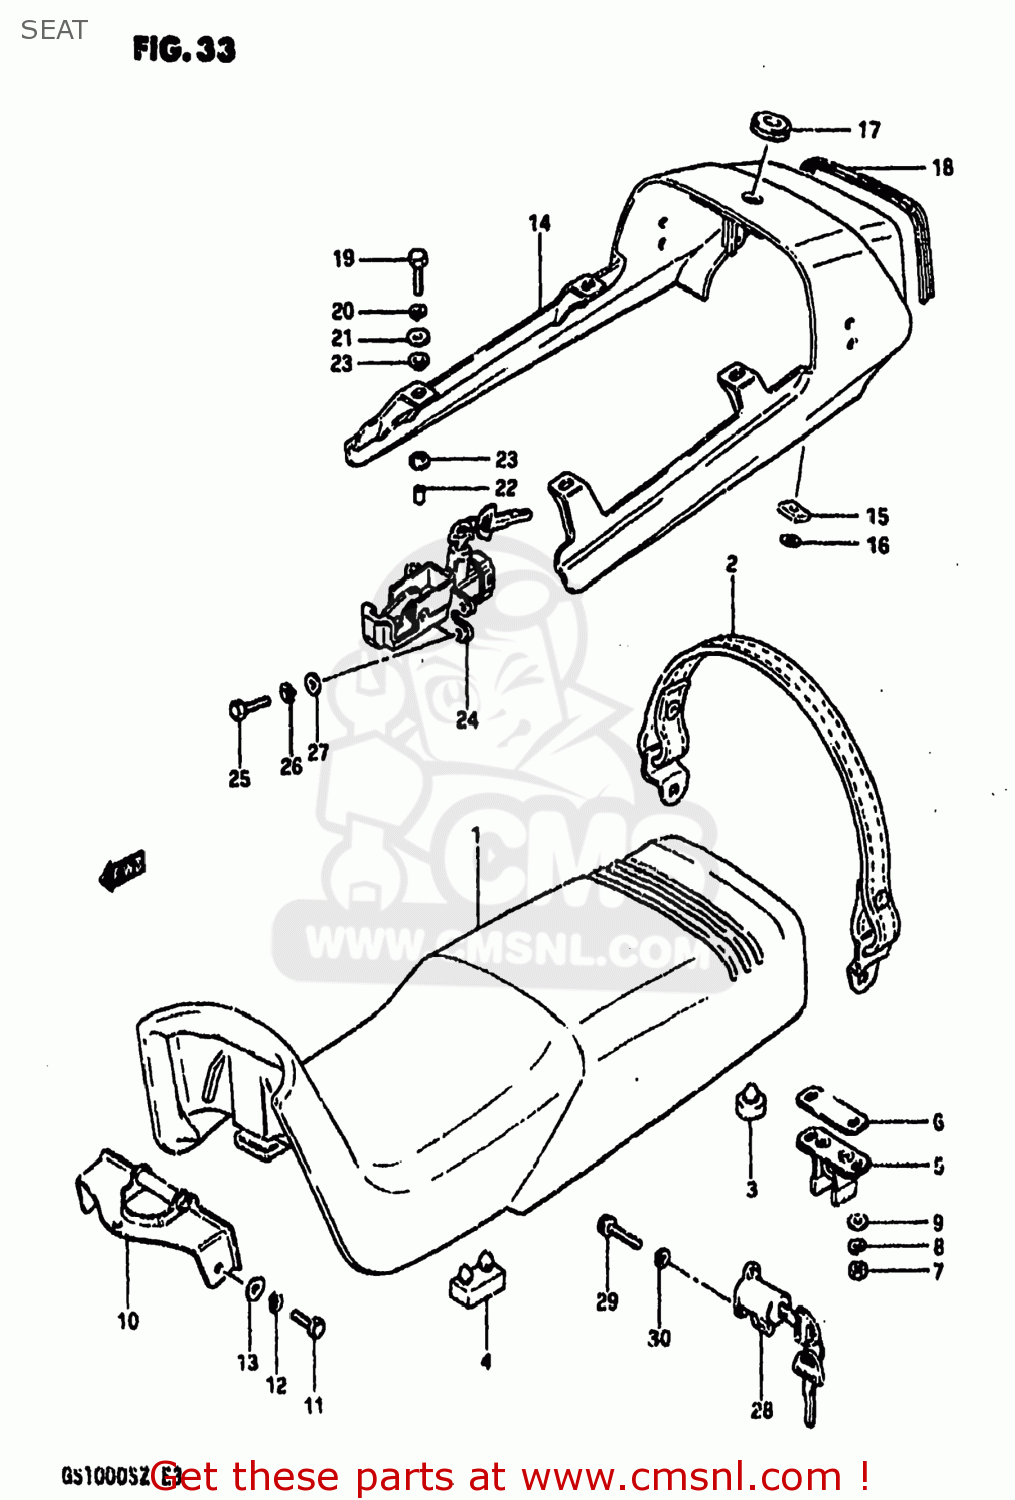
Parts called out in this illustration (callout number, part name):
1	SEAT ASSY
2	BAND,SEAT GRIP
3	CUSHION
4	CUSHION
5	STRIKER,SEAT LOCK
6	SHIM,SEAT LOCK STRIKER
7	NUT 6MM
8	LOCK WASHER
9	WASHER
10	PLATE,SEAT HOOK FR
11	BOLT
12	LOCK WASHER
13	WASHER
14	COVER ASSEMBLY,SEAT TAIL
15	CUSHION,SEAT TAIL
16	NUT
17	GROMMET,SEAT LOCK HOLE
18	MOLE,SEAT TAIL COVER
19	BOLT
20	LOCK WASHER
21	WASHER (6.5X24X1.6)
22	SPACER (7X10X12)
23	CUSHION
24	LOCK SET
25	BOLT
26	LOCK WASHER
27	WASHER
28	LOCK ASSEMBLY,HELMET
29	BOLT
30	LOCK WASHER
